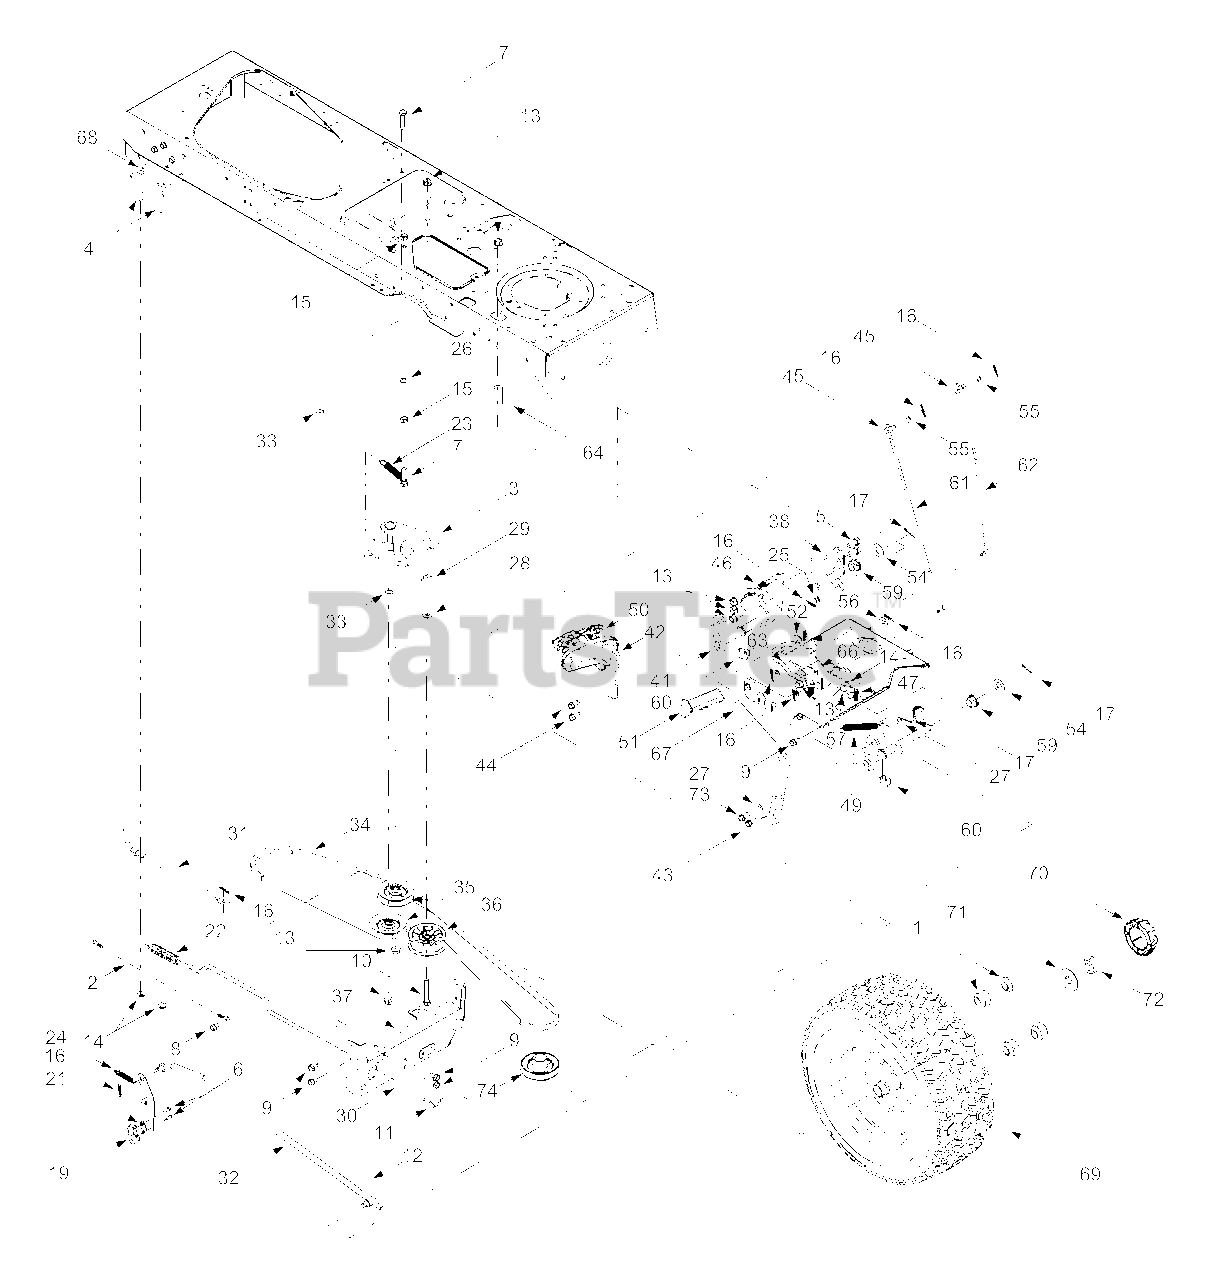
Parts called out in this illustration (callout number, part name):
1	Lug Nut, 3/4-16
2	Reverse/Ground Wire Harness Adapter
3	Double Idler Bracket Assembly
4	Hex Cap Screw, 5/16-18 x 2.75
5	Hex Cap Screw, 3/8-16 x .75
6	Screw, #8-18 x .5
7	Hex Cap Screw, 3/8-16 x 1.5
8	Self-tapping Screw, 1/4-20 x .50
9	Self-tapping Screw, 5/16-18 x .625
10	Hex Cap Screw, 3/8-16 x 2.25
11	Ferrule, 5/16-18
12	Ferrule, 3/8-24
13	Flange Lock Nut, 3/8-16
14	Flange Lock Nut, 5/16-18
15	Hex Nut, 3/8-16
16	Internal Cotter Pin
19	Short Spring Switch
20	Push-mount Cable Tie
21	Insulator Nut Plate
22	Extension Spring, .59 x 4.0
23	Extension Spring, .5 x 3.97
24	Extension Spring, 3/8 x 1.44
25	Flat Washer, .385 x .62 x .063
26	Lock Washer, 3/8
27	Flat Washer, .344 x .750 x .120
28	Flat Washer, .407 x .812 x .135
29	Shoulder Spacer, .38
30	Hydrostatic Control Rod
31	Hydrostatic Bypass Rod
32	Hydrostatic Brake Rod
33	Spacer, .376 x .625 x .22
34	Drive Belt
35	V-idler Pulley, 3.06
36	Flat Idler Pulley, 2.75
42	Hydro Pedal Assembly
43	Self-tapping Screw, 5/16-18 x .875
44	Self-tapping Screw, 5/16-18 x .75
45	Ferrule, 1/4-20
46	Pin, 3/8-16 x 2.43
47	Compression Spring, .40 OD x 1.17
48	Extension Spring, .50 OD x 1.41
49	Extension Spring, .50 OD x 6.37
50	Drive Pedal Pad
51	Brake Pedal Pad
52	Flat Washer, .411 x 1.25 x 1.0
53	Flat Washer, .281 x .50 x .063
54	Flat Washer, .64 x 1.24 x .06
55	Flat Washer, .344 x .062 x .03
56	Flat Washer, .406 x .875 x .105
57	Shoulder Screw, .437 x 1.62
58	Shoulder Screw, .5 x .434
59	Hex Flange Bearing
60	Split Hex Flange Bearing
61	Cruise Control Rod
62	Brake Lock Control Rod
63	Cruise Latch
64	Spacer, 5/16 x 1.54
66	Drive Lockout Bracket
70	Hub Cap
71	Flat Washer, .780 x 1.59 x .062
72	Jam Nut, 3/4-16
73	Self-tapping Screw, 5/16-18 x .75
74	Engine Pulley
